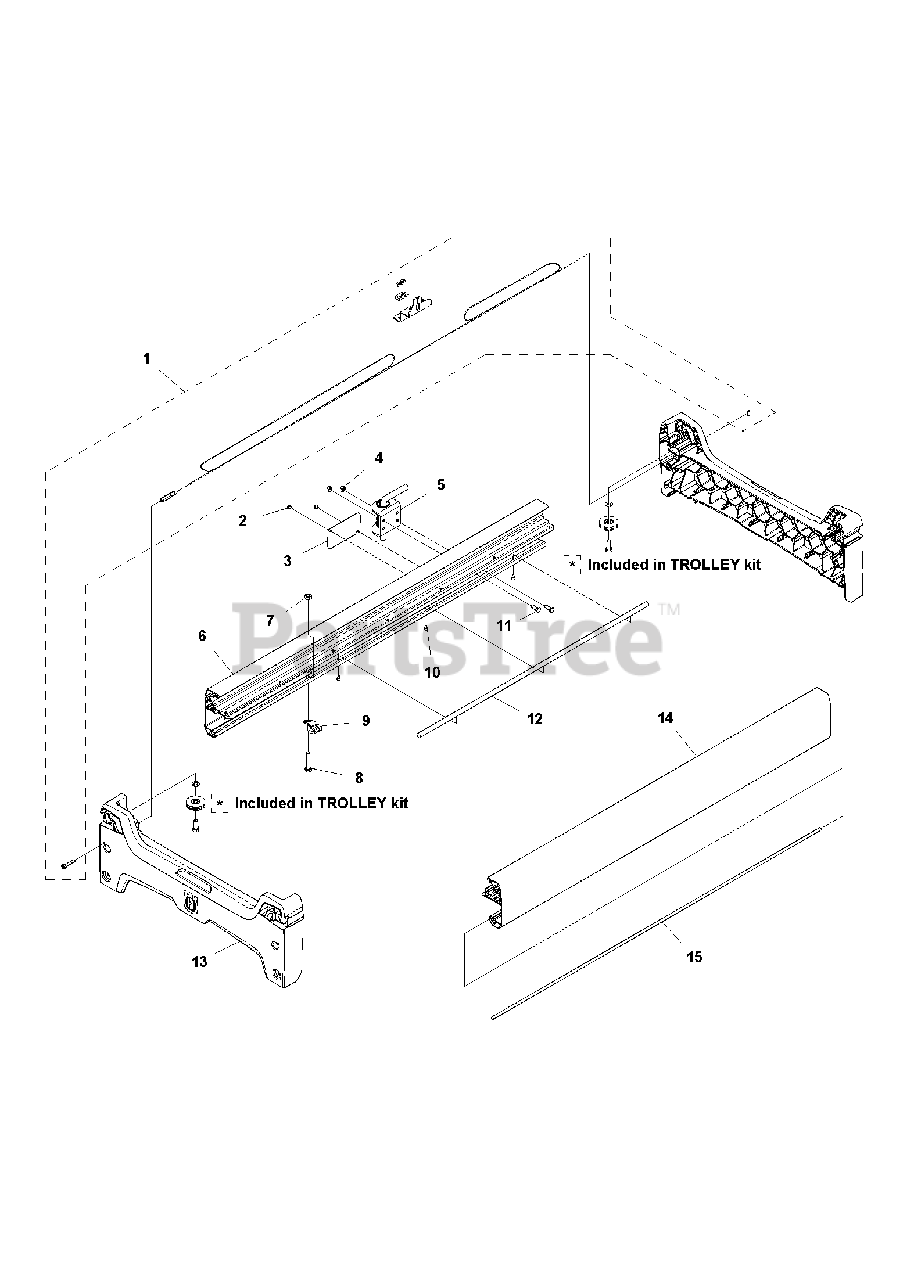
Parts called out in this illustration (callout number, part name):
2	SCREW CCRPANT
4	HEXAGON LOCKING NUT
7	HEXAGON LOCKING NUT
11	SCREW EHHM
